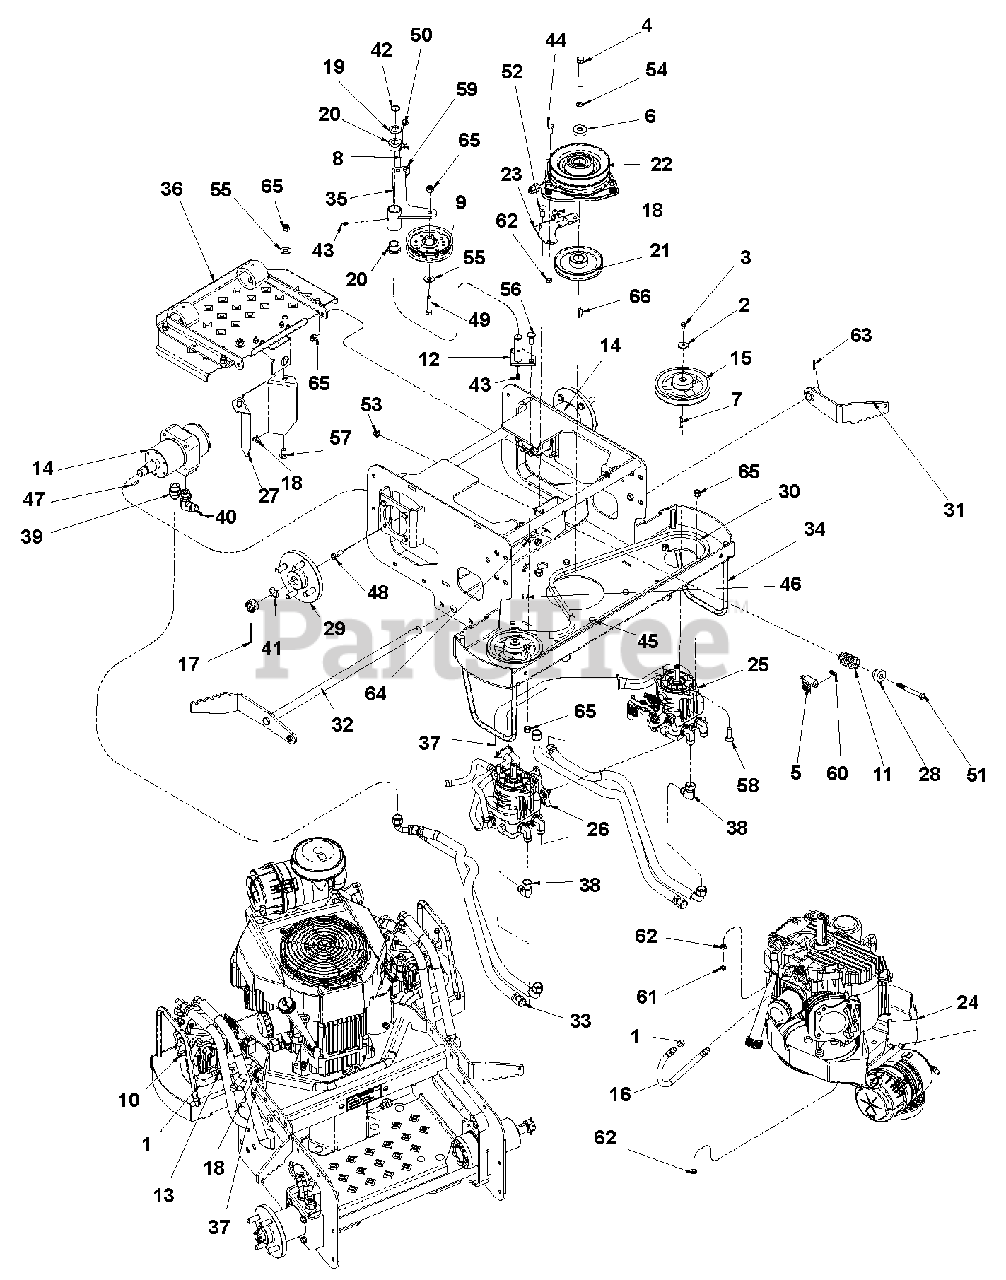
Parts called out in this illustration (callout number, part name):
1	Pipe Cap 3/8 NPT Female
2	Washer, .250 Wide Heavy Flat Y
3	Bolt, M6 x 1.00 x 10 Hex 8.8 Y
4	Bolt, 7/16-20 x 3.00 Hex 5 Y
5	Switch (N.0.)
6	Spacer, .468 x 1.38 x .375 Y
7	Key, M5 x M5 x M30 RD
8	Spring, Ext .900 x .135 x 4.50 Y
9	Pulley, V-belt 4.00 x .379 w/Bearing
10	Clamp, Hose - 1/2" Pinch
11	Spring, Com 1.22 x .162 x 2.50 Y
12	Weldment, Pivot Idler Mount
13	Fitting, Tun 3/8 Hose
14	Motor, Wheel HGM-12p-7172
15	Assembly, Pump Pulley w/Set Screw
16	Fitting, Oil Drain
17	Pin, Cot .125 x 2.00 EXTP Y
18	Tie Wrap, Black
19	Bushing, Machine .750 x 1.25 x .048
20	Bearing, Flange .750 x 1.000 x .750 x 1.250
21	Pulley, V-belt 4.78pd x 1.000
22	Clutch Assembly, Ogura
23	Plate, Clutch Dog
24	Engine, Kawasaki 16hp F x 481
25	Assembly, Hyd Pump
26	Assembly, Hyd Pump
27	Cover, Operator Presence Control
28	Washer, Spring Y
29	Assy, Rear Wheel Hub
30	Belt, HA 68.2 EL AMD OHR
31	Weldment, Brake Arm Right Hand
32	Weldment, Brake Shaft Left Hand
33	Hose, Hyd 1/2 x 26-1/2 Ezflex
34	Weldment, Frame 34 w/Decals
35	Weldment, Idler Pivot
36	Assy, Foot Plate (see page 8)
37	Abrasion Sleeve
38	Adapter, .75 FESW x 3/4 MJIC X 90
39	Adapter, Hydraulic Steel 7/8 "O" To .75
40	Adapter, 8MJ-10MB90
41	Shim, .020 x .787 x 1.102
42	Ring, Retaining-External .750 x .042
43	Grease Zerk, .25-28 Straight .69 LG
44	Bolt, Hex .31-18 x .75 Grade 5
45	Bolt, Hex .38-16 x 1.25 FTH Grade 5 EP80YZ
46	Bolt, Hex .31-18 x 1.75 Grade 5
47	Key, Woodruff .1875 x .75
48	Bolt, 3/8-16 x 1.00 Hex 5
49	Bolt, 3/8-16 x 1.75 Hex 5
50	Bolt, 3/8-16 x 2.50 Hex 5
51	Bolt, 3/8-16 x 3.25 Hex 5
52	Bolt, 7/16-14 x .750 Hex 5
53	Nut-Hex .31-18
54	Washer, .375 Medium Spring Lock Y
55	Washer-Flat-Steel .438 x 1.00 x .083
56	Bolt, Round Head Square Neck .38-16 x 1.00 Grade 5
57	Bolt, Round Head Square Neck .38-16 x 1.00 Grade 5
58	Bolt, Round Head Square Neck .38-16 x 1.25 Grade 5
59	Nut, .38-16 Jam Grade 5
60	Nut-Locking-Nylon 10-24 with Insert
61	Nut-Jam .312-18
62	Nut-Locking-Nylon .312-18
63	Pin-Roll .156 x 1.00
64	Screw, Machine 10-24 x .625 Panhead
65	Nut-Locking-Nylon .38-16
66	Key, .250 x .250 x .995 TPR
